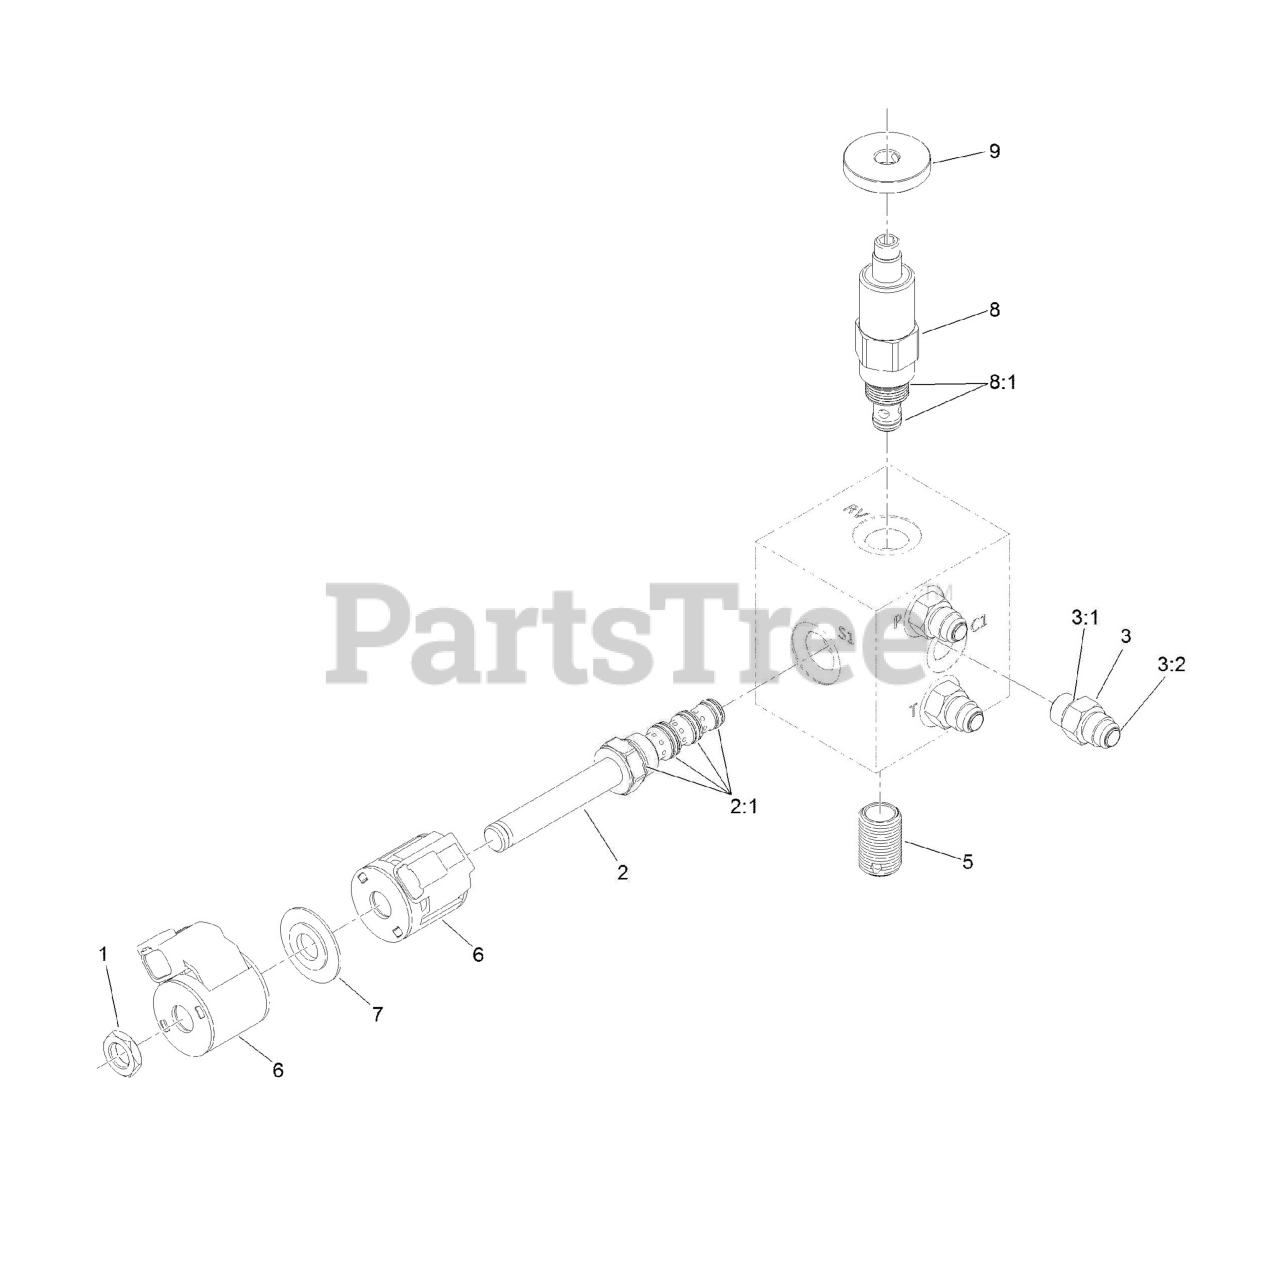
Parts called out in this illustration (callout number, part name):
1	NUT-COIL
2	VALVE-SOLENOID
2:1	Seal Kit
3	FITTING-STRAIGHT
3:1	BOSS O-RING
5	Nipple-Filter
6	E Coil-12V Dc
7	Spacer-Coil
8	VALVE-RELIEF, POPPET TYPE
8:1	SEAL KIT
9	KNOB (1.5 DIA)
